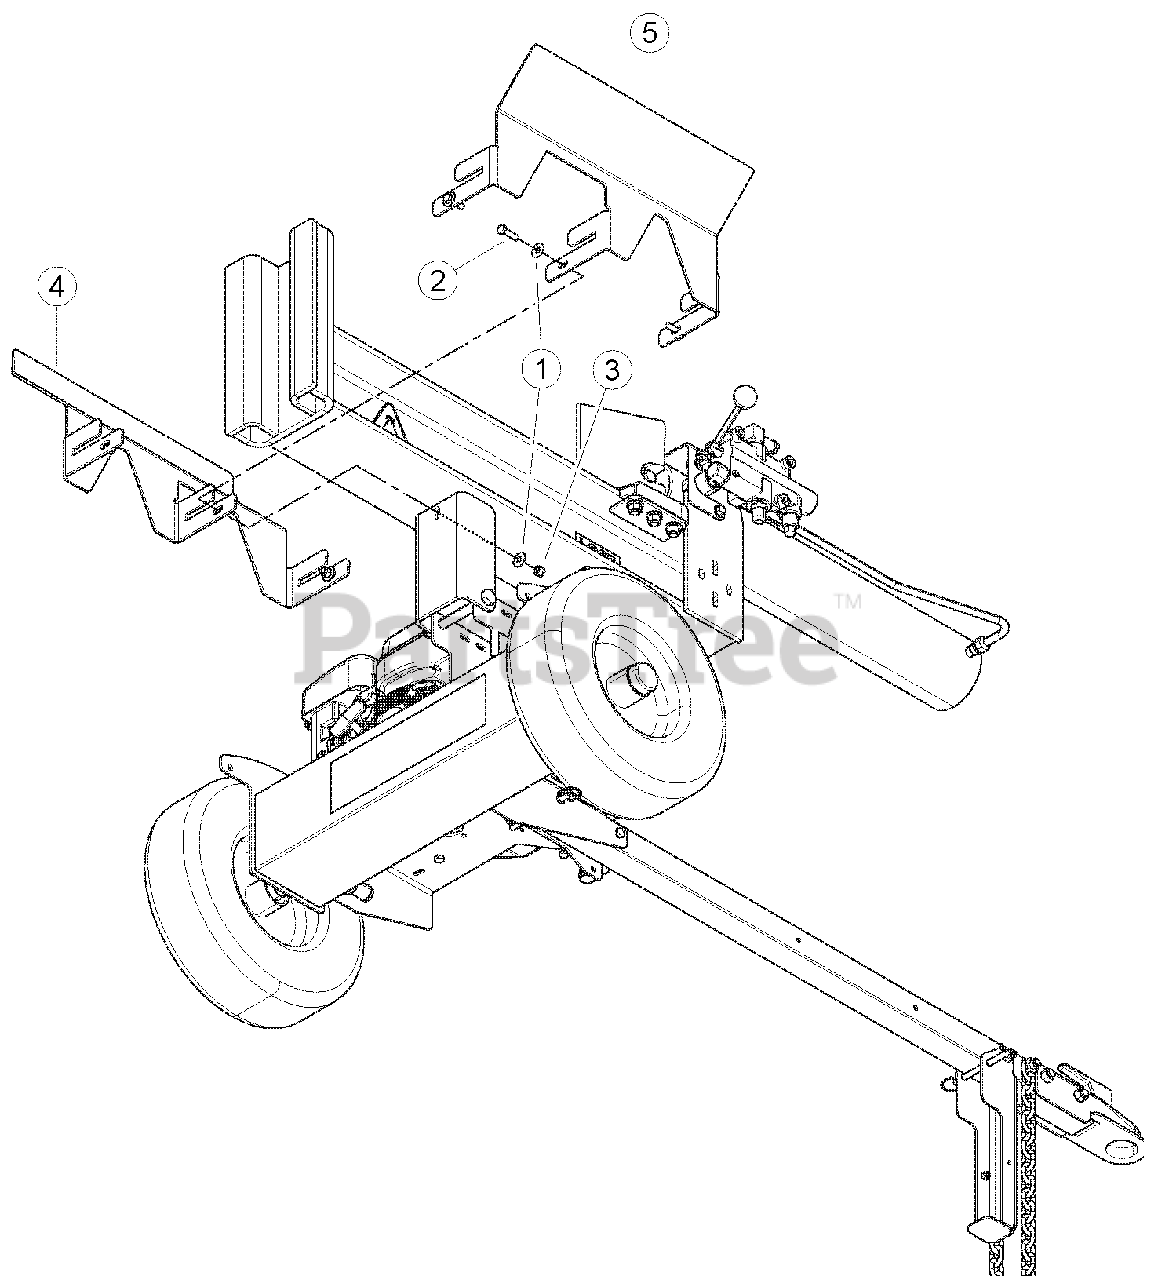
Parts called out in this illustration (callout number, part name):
1	WASHER, 3/8 FLAT ZP
2	BOLT, 3/8 X 1-1/4 HEX HD GR5 ZP
3	NUT, 3/8 NE NYLOCK ZP
4	CRADLE, LOG SPLITTER
5	CRADLE, LOG SPLITTER
